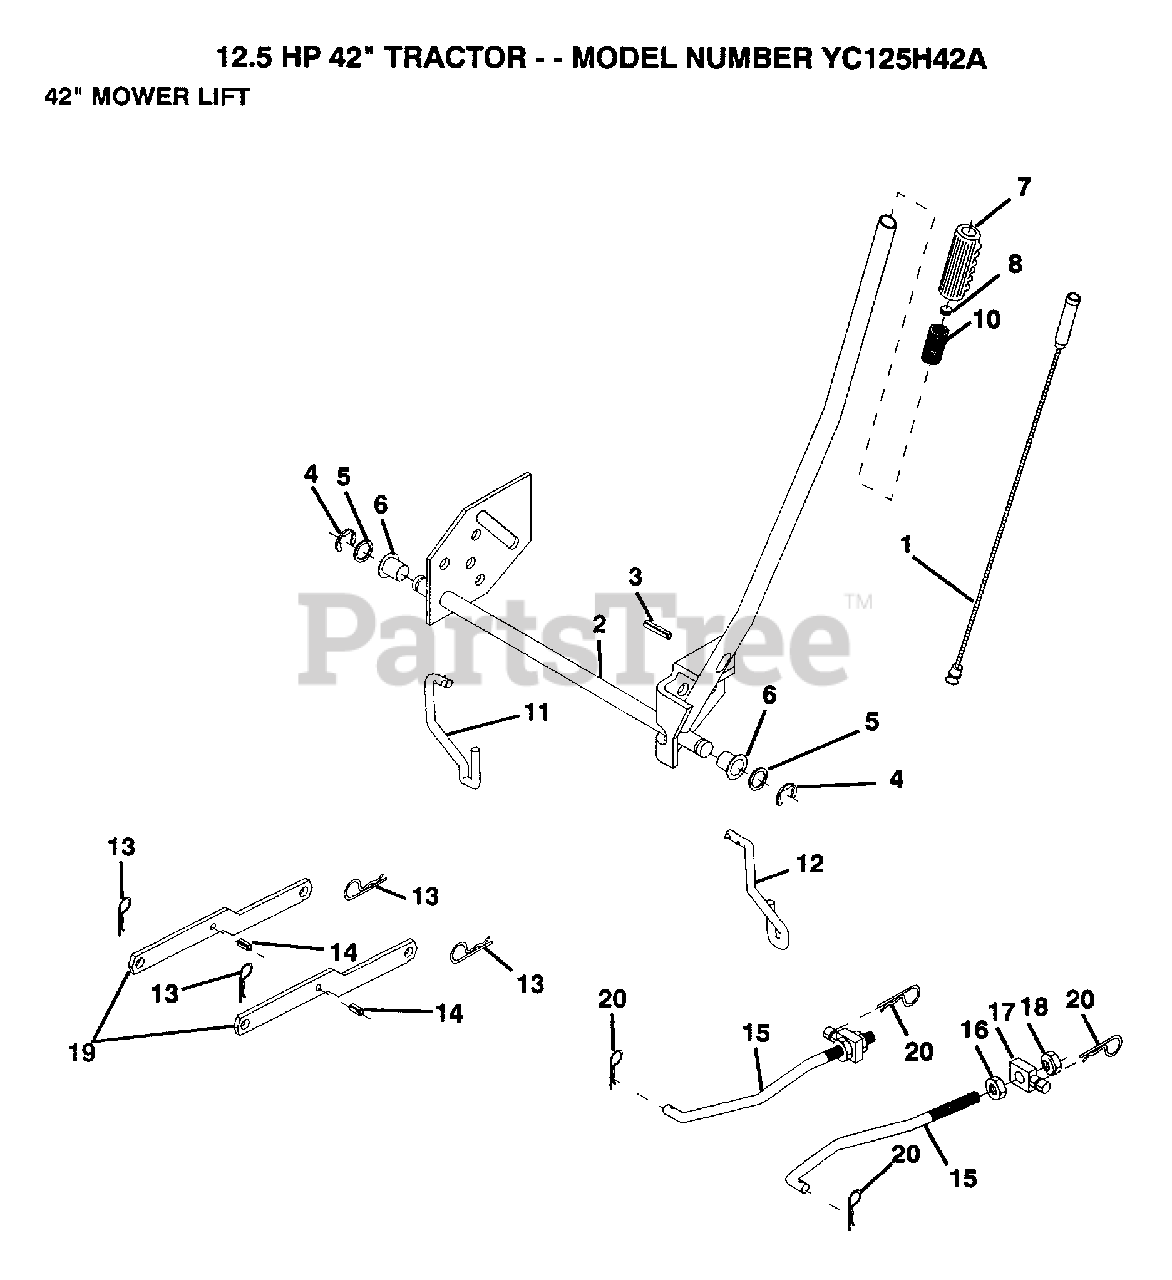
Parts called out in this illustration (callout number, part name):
1	WIRE ASM
3	PIN-GROOVE LT
5	WASHER
6	NYLON BEARING
7	GRIP
11	LINK LIFT LH
12	LIFT LINK RH
14	"PIN,SPRING"
15	LINK.FRONT
16	NUT
17	TRUNION
18	NUT.LK.W/WSH.1/2.
20	RETAINER.SPRING
